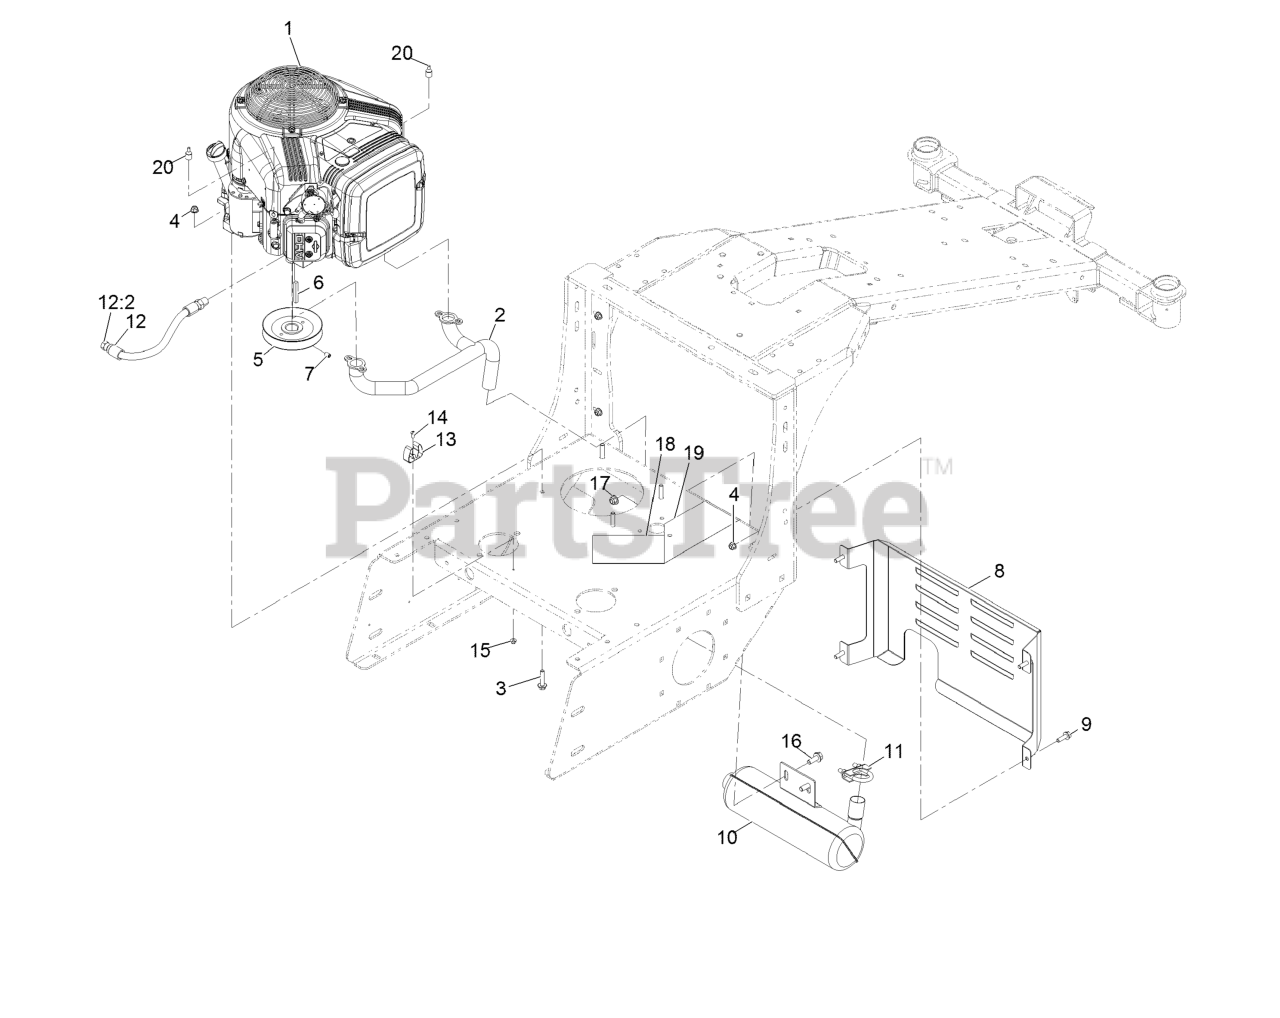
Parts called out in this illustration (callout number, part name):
1	Engine - Vanguard
2	18 HP EXHAUST MANIFOLD 4
3	SCREW-HHF
4	NUT-HF, NI
5	PULLEY-DRIVE
7	Setscrew-HSH
8	GUARD-ENGINE, AE
9	SCREW-HH
10	23HP BRIGGS MUFFLER(18HP
11	Clamp-Muffler
12	HOSE-DRAIN,3/8X15.75W/JIC
13	Holder-Tool, Clip
14	Screw-HSBH
15	Nut-Hex Flange
16	SCREW-HHF 3/8-16 X 1
17	NUT-HF, NI
18	ADHESIVE BACK, HEAT BARRI
19	TAPE-HEAT
20	Tube-Heat Shrink, 1/2
